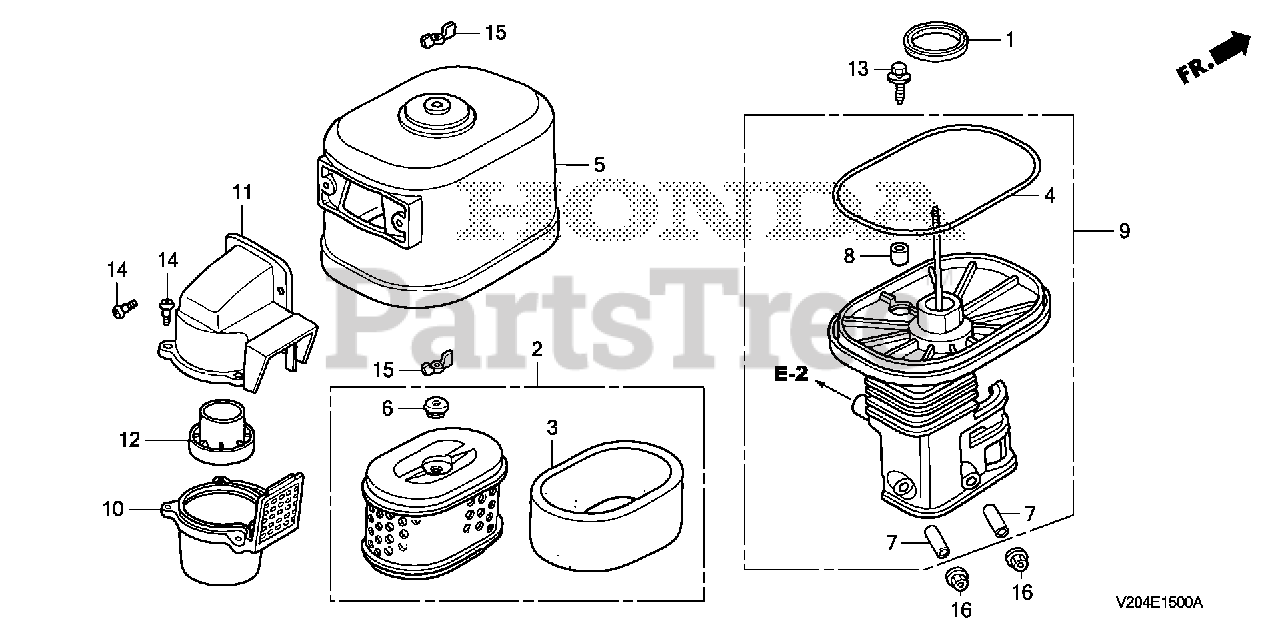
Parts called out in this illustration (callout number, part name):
1	GASKET, ELBOW
2	ELEMENT, AIR CLEANER
3	FILTER (OUTER)
4	SEAL, AIR CLEANER COVER
5	COVER, AIR CLEANER (CYCLONE)
6	GROMMET, AIR CLEANER
7	COLLAR, AIR CLEANER
8	COLLAR B, AIR CLEANER
9	ELBOW, AIR CLEANER
10	CASE, PRE AIR CLEANER
11	CAP, PRE AIR CLEANER
12	GUIDE, PRE AIR CLEANER
13	BOLT-WASHER (6X22)
14	SCREW, PAN (5X16.5)
15	WINGNUT, TOOL BOX SETTING
16	NUT, FLANGE (6MM)
